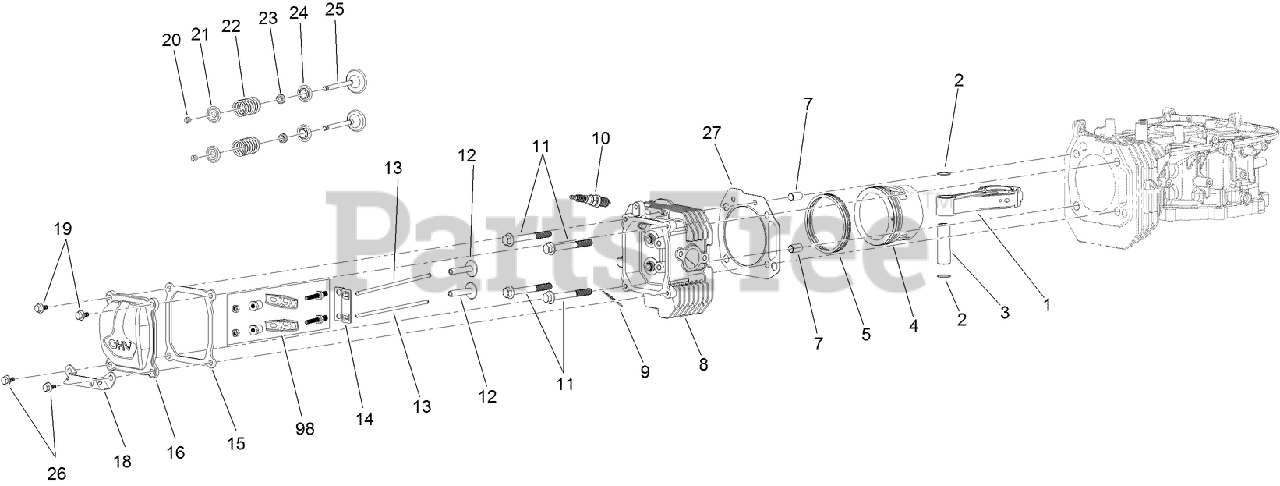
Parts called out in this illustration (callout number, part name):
1	CONNECTING ROD ASM
2	RING-RETAINING, PISTON PIN
3	PIN-PISTON
4	PISTON
5	RING SET
7	PIN-DOWEL
8	HEAD-CYLINDER
9	GASKET-EXHAUST
11	SCREW-HHF
12	LIFTER-VALVE
13	ROD-PUSH
14	PLATE-GUIDE, PUSH ROD
15	GASKET-COVER, VALVE
16	COVER-VALVE
18	BRACKET-MUFFLER
19	SCREW-SHOULDER, HHF
20	KEEPER-VALVE
21	RETAINER-SPRING, VALVE
22	SPRING-VALVE
23	SEAL-STEM, VALVE
24	SEAT-SPRING, VALVE
25	VALVE SET
26	SCREW-SHOULDER, HHF
27	GASKET-CYCLINDER
